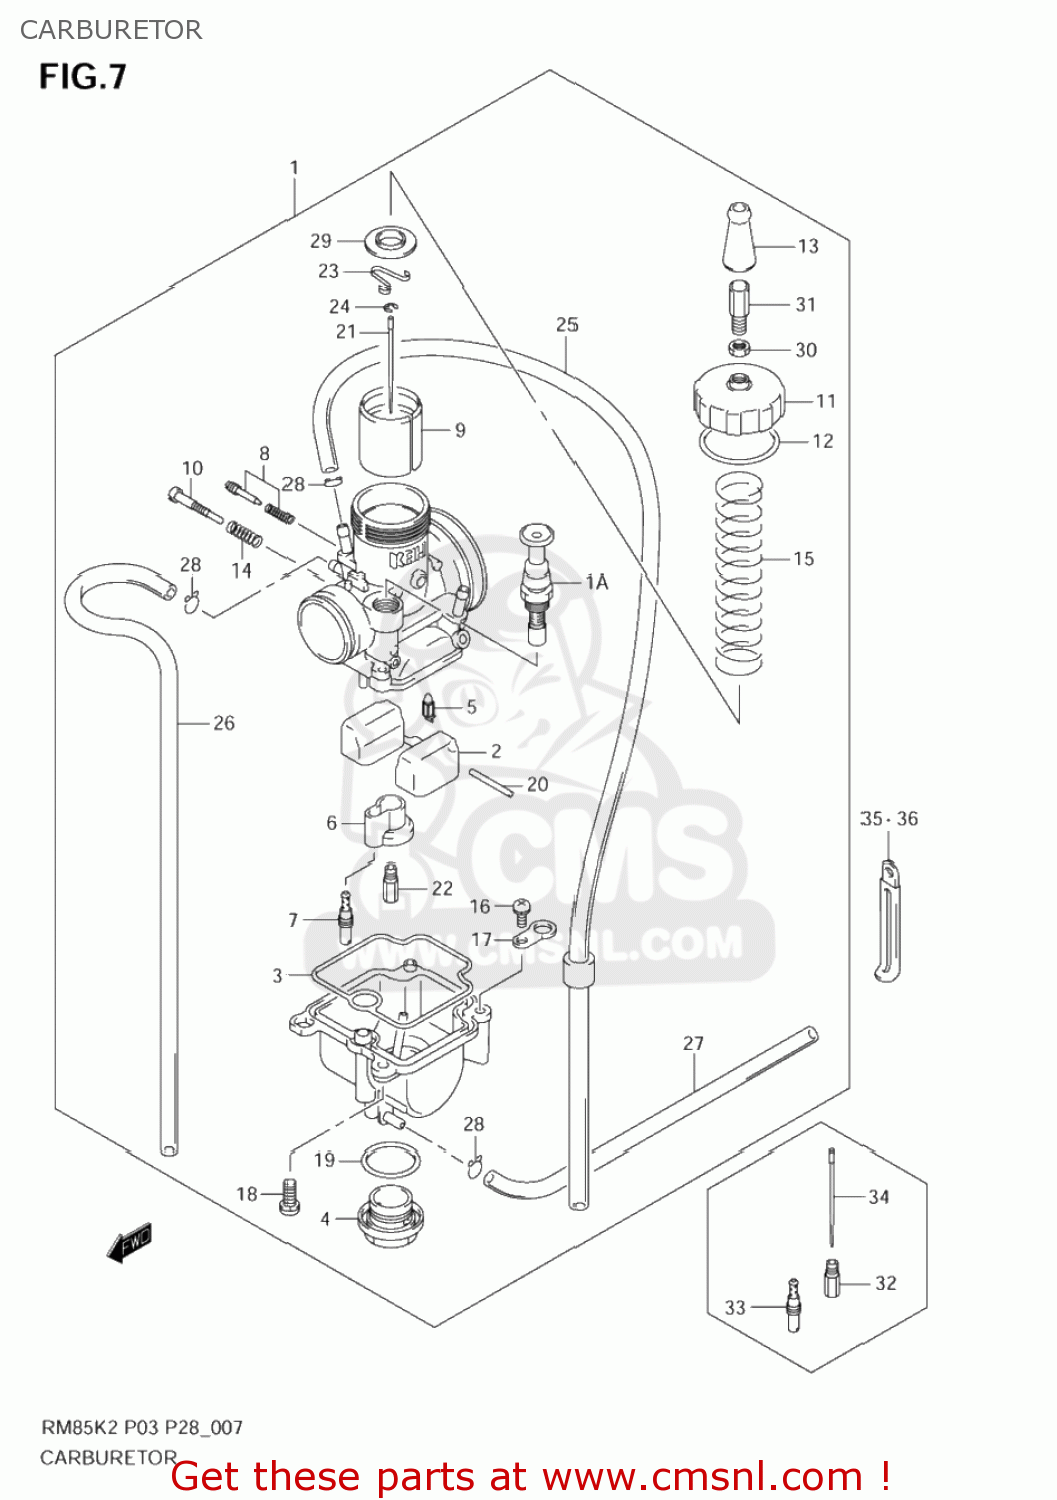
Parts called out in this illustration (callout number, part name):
1	CARBURETOR ASSY
1A	VALVE ASSY,STARTER
2	FLOAT ASSY
3	GASKET (NAS)
4	BOLT,DRAIN
5	VALVE ASSY, NEEDLE
6	HOLDER,JET
7	JET,SLOW(50)
8	ADJUST SCREW SET
9	THROTTLE VALVE
10	SCREW,STOP
11	COVER
12	GASKET (NAS)
13	CAP
14	SPRING
15	SPRING
16	SCREW
17	PLATE
18	SCREW
19	O RING
20	PIN,FLOAT
21	NEEDLE(24NAAH)
22	JET,MAIN(125)
23	CLIP
24	CLIP,NEEDLE
25	PIPE ASSY
26	HOSE(4X7X620)
27	HOSE(4X7X620)
28	CLIP
29	PLATE
30	NUT
31	ADJUST BOLT
32	JET,MAIN(115)
33	JET,SLOW(48)
34	NEEDLE(24NAAF)
35	CLAMP(L:45)
36	CLAMP(L:65 T:0.8)
